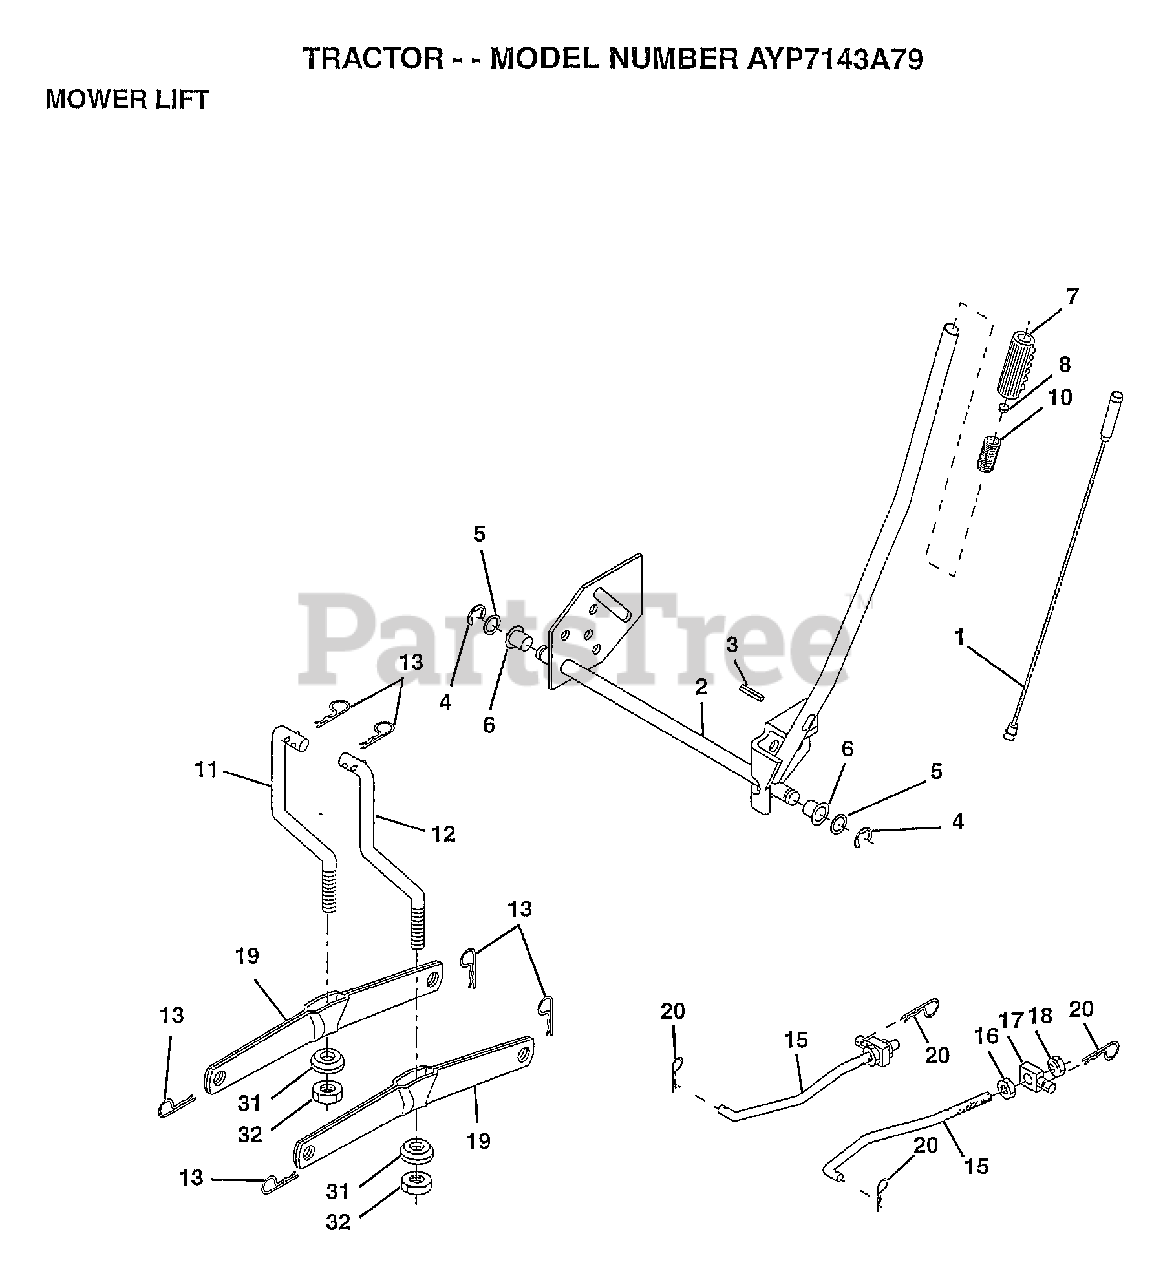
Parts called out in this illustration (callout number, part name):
1	WIRE ASM
2	SHAFT.LIFT.ASM.RH
3	PIN-GROOVE LT
5	WASHER
6	NYLON BEARING
7	GRIP
15	LINK.FRONT
16	NUT
17	TRUNION
18	NUT.LK.W/WSH.1/2.
19	ARM SUSP REAR
20	RETAINER.SPRING
31	BEARING PVT LH
32	NUT.CROWNLOCK.3/8
